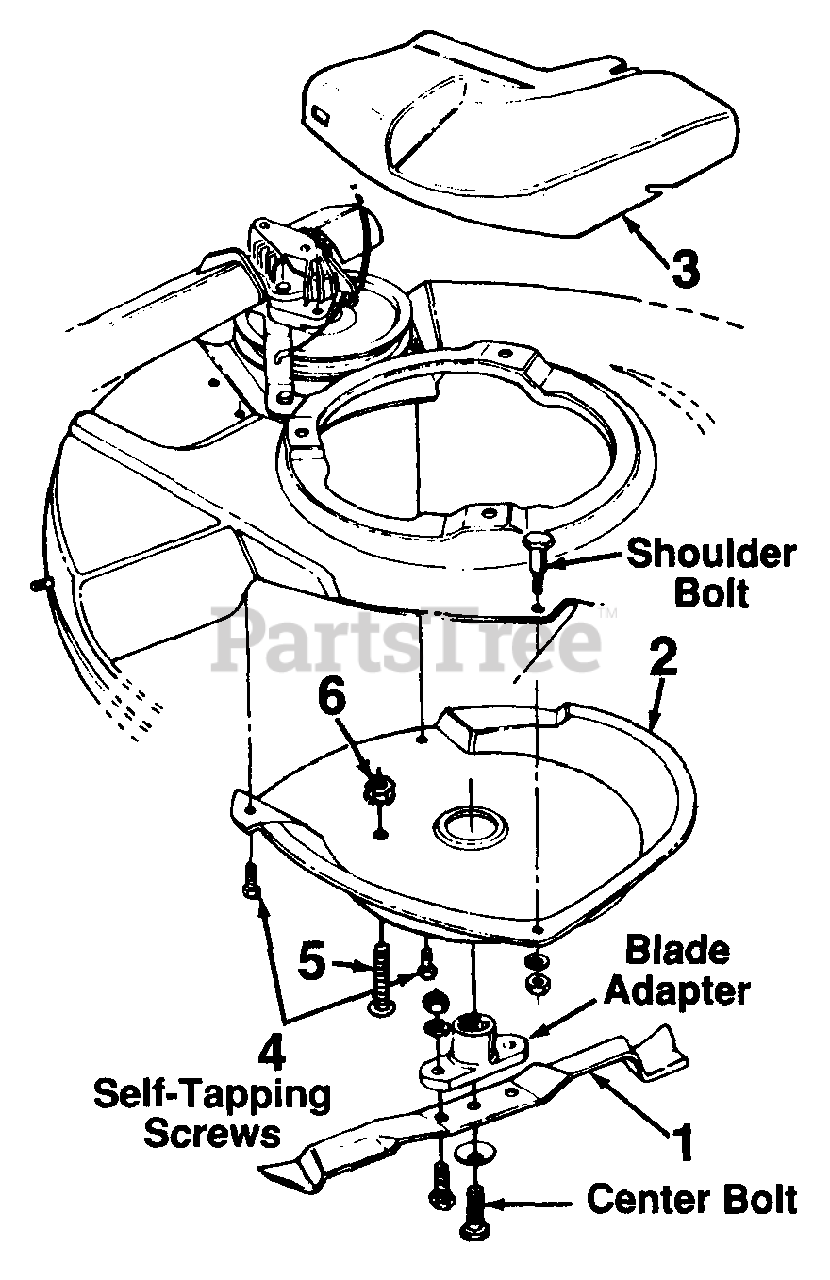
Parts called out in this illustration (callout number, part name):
1	Mulching Blade
4	Self-Tapping Screw
5	Phillips Scr. 1/4-20 x 1.5" Lg.
6	Hex Sems Nut 1/4-20 Thd.
